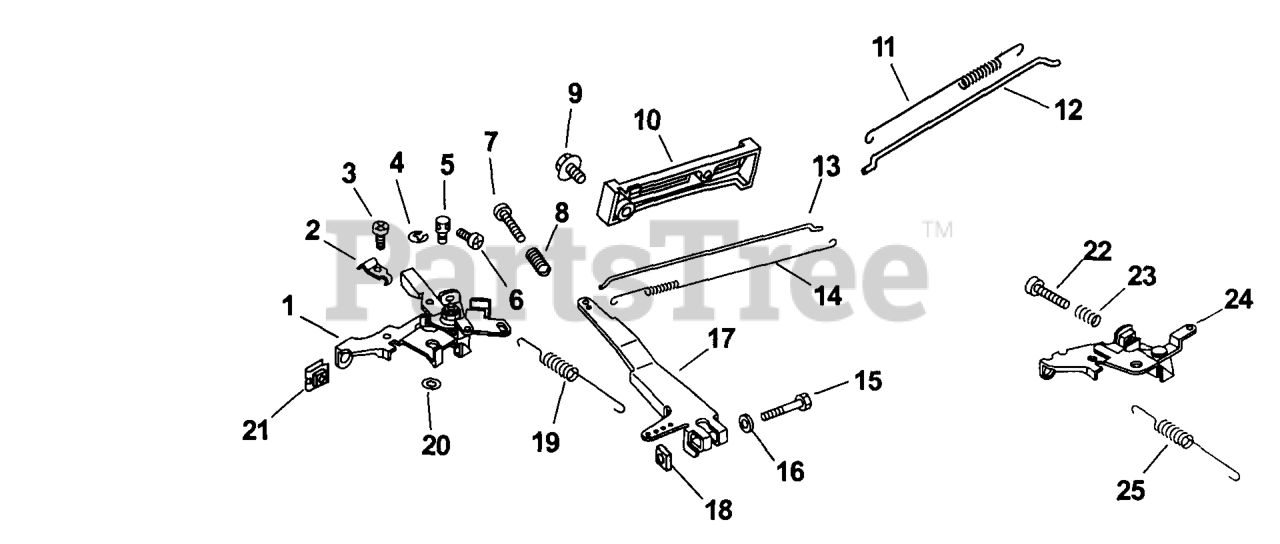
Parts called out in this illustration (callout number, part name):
1	LEVER, THROTTLE
2	BOWDEN CLAMP (#DSC)
5	CLAMP, WIRE -USE 63 237 13-S
7	SCREW, PAN HEAD
8	SPRING, COMPRESSION
10	CONTROL PANEL
11	SPRING, CHOKE
12	LINKAGE, CHOKE
13	LINKAGE, THROTTLE
14	SPRING, LINKAGE-(#DSC)
17	LEVER, GOVERNOR
19	SPRING, GOVERNOR
6311302-S	DECAL, CHOKE
